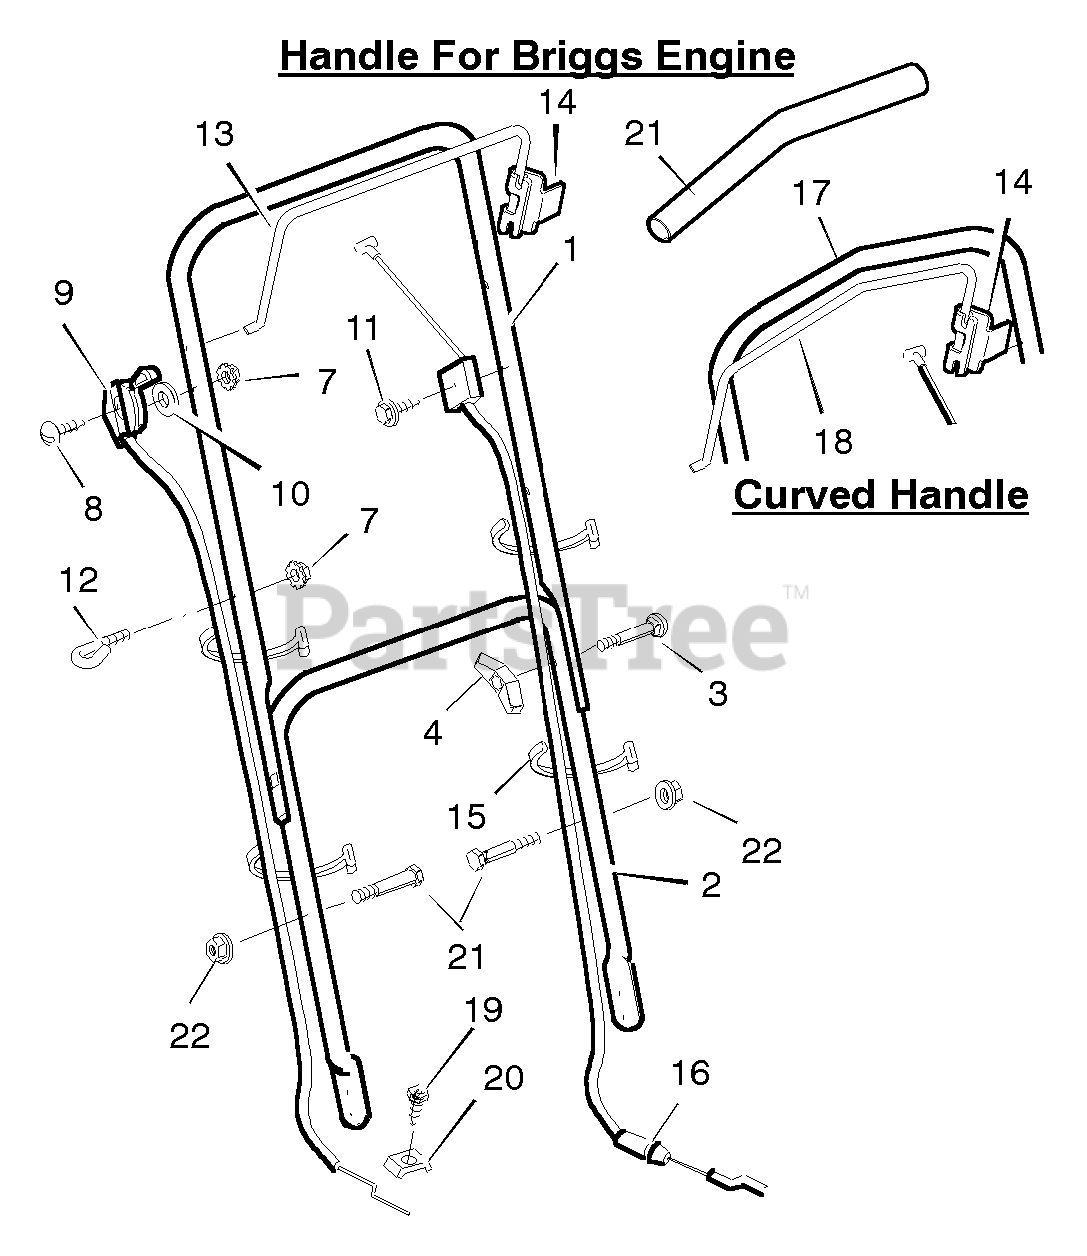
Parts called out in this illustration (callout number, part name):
1	Handle, Upper-Straight
2	Handle, Lower (Black)
4	Knob, Plastic
7	Locknut
9	Throttle Control
10	Washer
12	GUIDE, ROPE
13	Engine Stop Lever-Straight
14	Bracket, Stop Lever
15	Fastener, Cable
16	Engine Stop Cable
17	Handle, Upper- Curved
18	Engine Stop Lever-Curved
